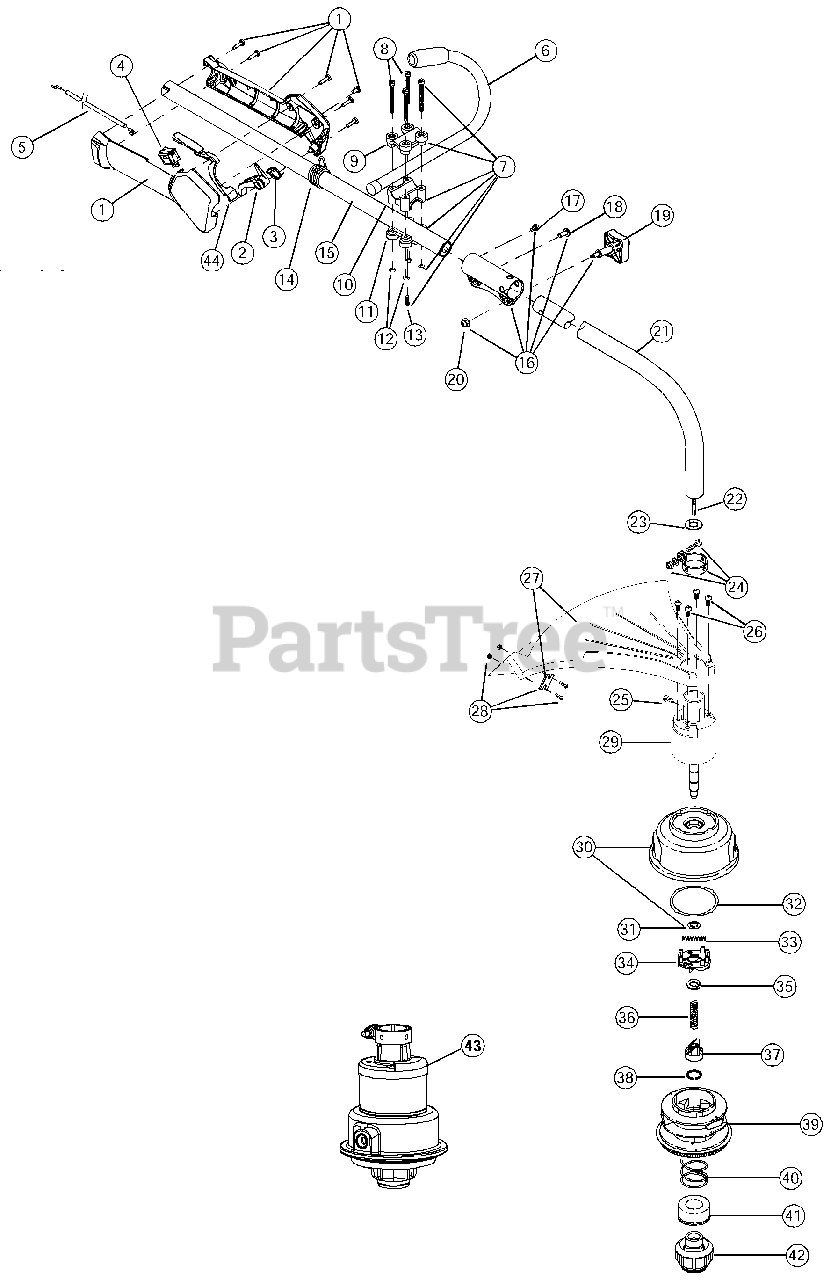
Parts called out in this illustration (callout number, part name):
1	Throttle Housing and Trigger Assembly
2	Throttle Trigger
3	Throttle Trigger Spring
4	Switch Assembly
5	Throttle Cable
6	J-Handle Assembly
7	Handle Bracket Assembly
9	Upper Handle Clamp
10	Middle Handle Clamp
11	Lower Handle Clamp
13	Anti-Rotation Screw
14	Harness Clip
15	Upper Drive Shaft Housing Assembly
16	EZ-Link(TM) Coupler
19	Adjustment Knob
20	Knob Retaining Nut
21	Lower Drive Shaft Housing Assembly
22	Lower Flexible Drive Shaft
23	Palnut
24	Lower Clamp Assembly
25	Anti-Rotation Screw
26	Shield Mounting Hardware
27	Shield and Blade Assembly
28	Blade Assembly
29	Bushing Housing Assembly
30	Outer Spool Assembly
31	Retaining Ring
32	Thrust Washer
33	Small Spring
39	Inner Reel
40	Large Spring
42	Bump Head Knob Assembly
43	Complete Cutting Head Assembly
44	Throttle Trigger Lock-Out
